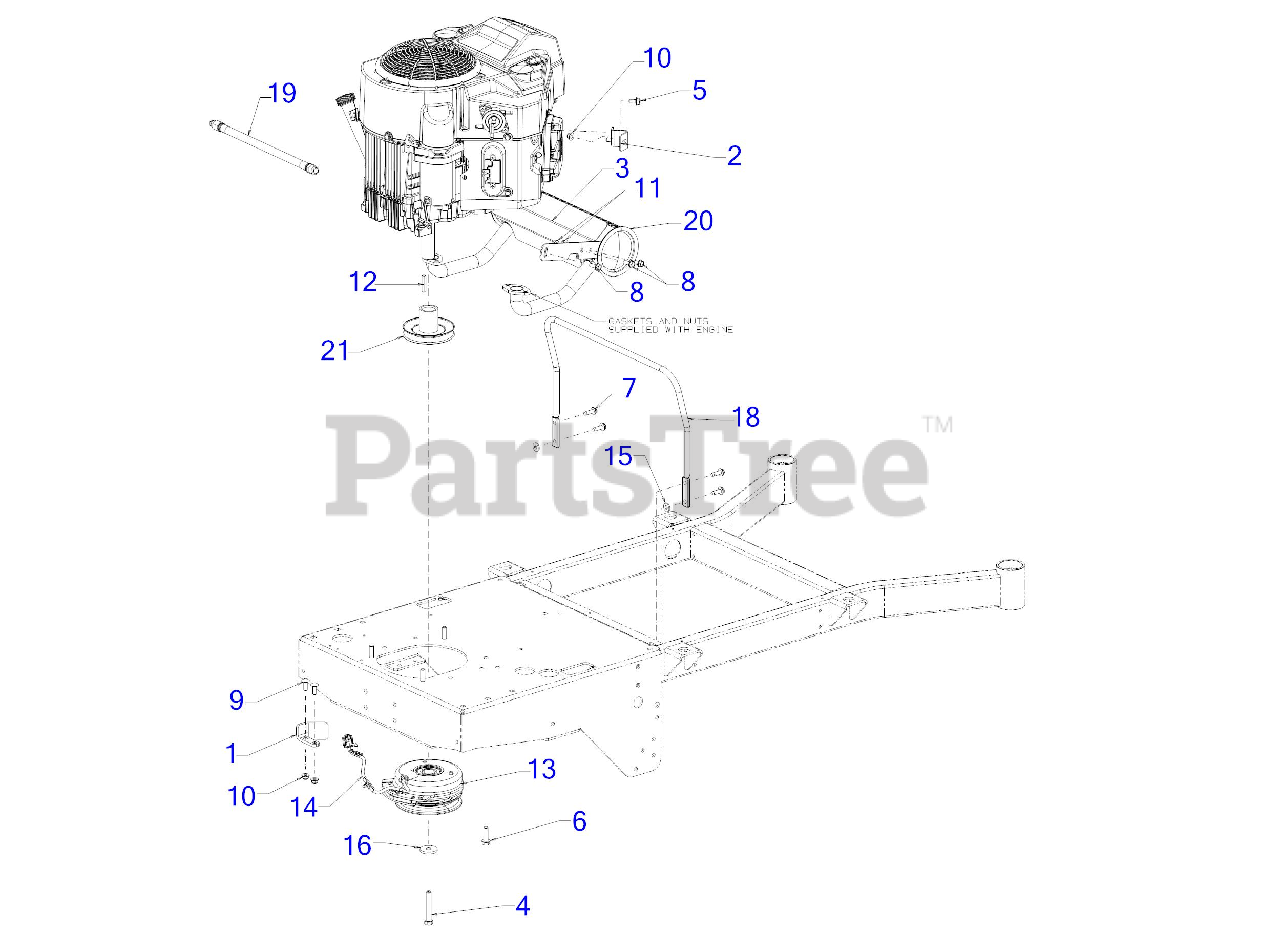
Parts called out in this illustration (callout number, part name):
1	PTO CLUTCH RETAINER BRACKET
2	MUFFLER MOUNTING BRACKET
3	MUFFLER SHIELD
4	SCREW 7/16-20:2.75 GR5
5	SCREW M8 x 1.25 x 16MM GR8.8
6	SCREW 3/8-16 x 1.25 GR5
7	SCREW 5/16-18 x 1.00
8	SCREW 5/16-18 x .750 GR8
9	BOLT 5/16-18X .875 GR1
10	FLANGE LOCK NUT 5/16-18
11	FLANGE NUT
12	SQUARE KEY 1/4 x 1.50
13	PTO CLUTCH 36" WAM
14	CLUTCH HARNESS 11"
15	FLAT WASHER
16	FLAT WASHER .45 x 1.5 x .172 HT
18	MUFFLR ROD
19	OIL DRAIN HOSE
20	MUFFLER (ROUND)
21	ENGINE PULLEY 1.125"
